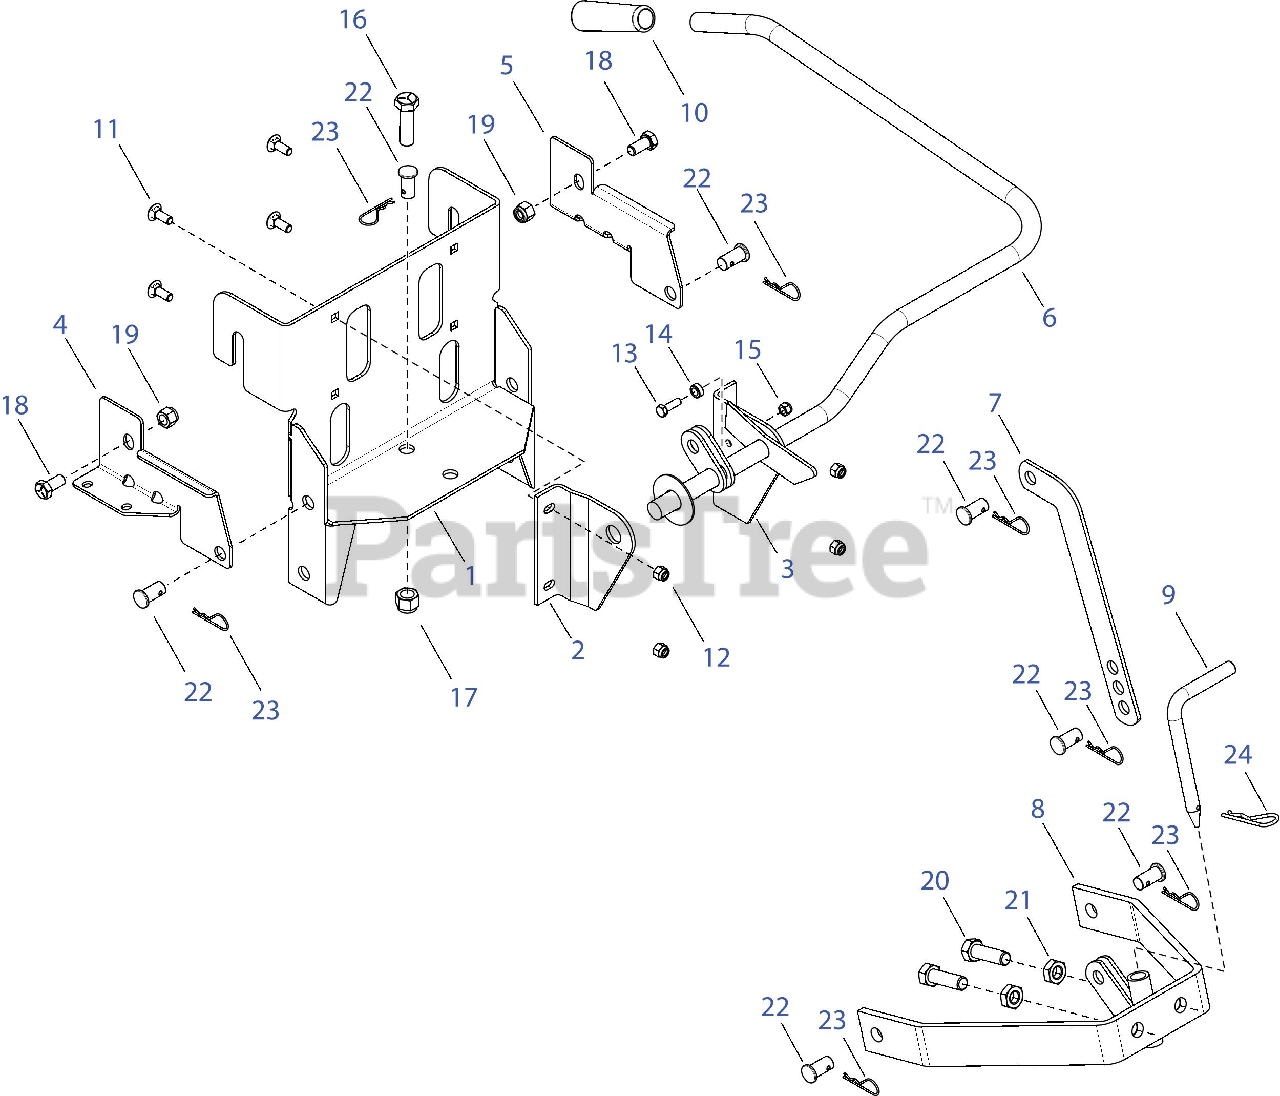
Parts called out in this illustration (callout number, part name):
1	Sleeve Hitch Frame
2	Pivot Bracket, L.H.
3	Pivot Bracket, R.H.
4	Hitch Support Bracket, L.H.
5	Hitch Support Bracket, R.H.
6	Lift Lever Assembly
7	Lifting Link Plate
8	Sleeve Hitch Lift Assembly
9	Pin, Sleeve Hitch
11	Bolt, Carriage 3/8-16 x 1"
12	Nylock Nut, 3/8-16
13	Bolt, Hex 5/16-18 x 1"
15	Nut, Nylock 5/16-18
16	Bolt, Hex 5/8-11 x 1-3/4"
17	Nut, Hex 5/8-11 Nylock
18	Bolt, Hex 1/2-13 x 1"
19	Nut, Nylock 1/2-13
20	Bolt, Hex 5/8-11 x 2"
21	Nut, Hex Jam 5/8-11
22	Clevis Pin, 5/8" x 1.2"
23	Pin, Hair Cotter, 3/32"
24	Pin, Hair Cotter, 5/32"
